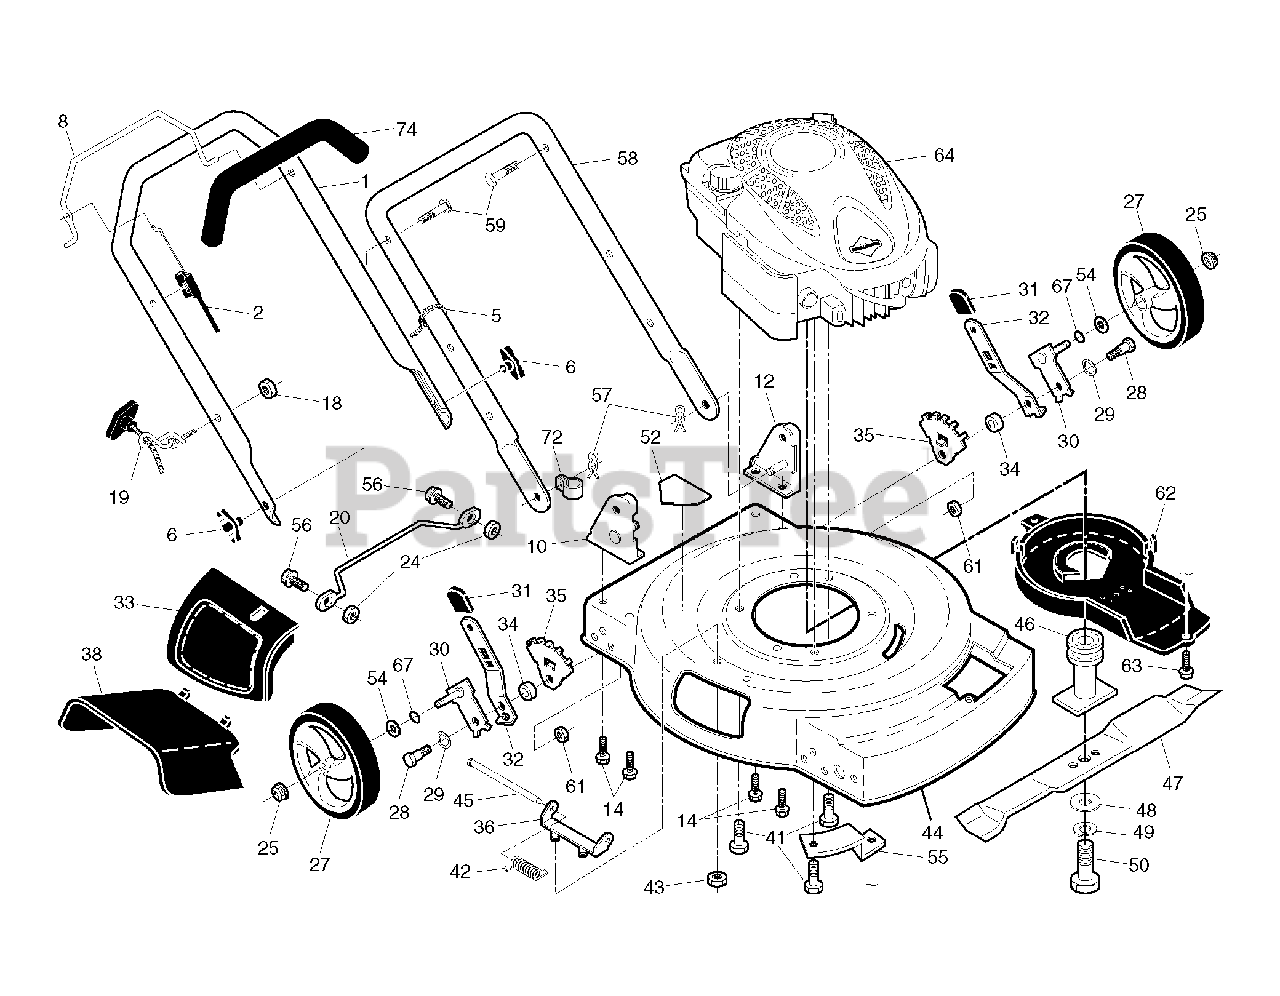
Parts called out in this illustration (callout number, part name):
2	CABLE.MZR
5	TIE GUIDE
6	KNOB, DEFLECTOR
10	HANDLE BRACKET ASM. RH
12	HANDLE BRACKET ASM. LH
14	SCREW 5/16-18
18	NUT
19	GUIDE.ROPE.STD.BLK.ZIN
25	NUT.HEX.FLANGE.3/8-16.LOCKNUT
28	BOLT SHOULDER 3/8 -16X1
29	WASHER FLAT
30	AXLE ARM ASSY.
31	SELECTOR KNOB
32	SPRING.SEL.EXT.21.DOMED.12/14
34	SPACER.HEIGHT.ADJUSTER
35	BRACKET.ADJ.WHEEL.5POS.ADS
36	HINGE BRACKET
41	BOLT 3/8-16X1-1/8
42	TORSION SPRING
43	LOCKNUT
45	ROD.HINGE.COMBI-C
46	ADAPTER.BLADE/PULLEY.25M
48	WASHER,HARDEN
49	LOCKWASHER
50	SCREW, HEX HD 3/8-24 X 1-3/8
52	DECAL.INTERNATIONL.CUTFINGER
54	WASHER PM
55	BRACKET
57	HAIRPIN COTTER
59	BOLT, HANDLE 5/16-18X1.75
61	LOCKNUT
62	DEBRIS SHIELD
63	SCREW.HEX.WSH
67	O-RING..070X.487.NEOPRENE
72	CLIP.CABLE.BLK
74	GRIP.HANDLE.FOAM
